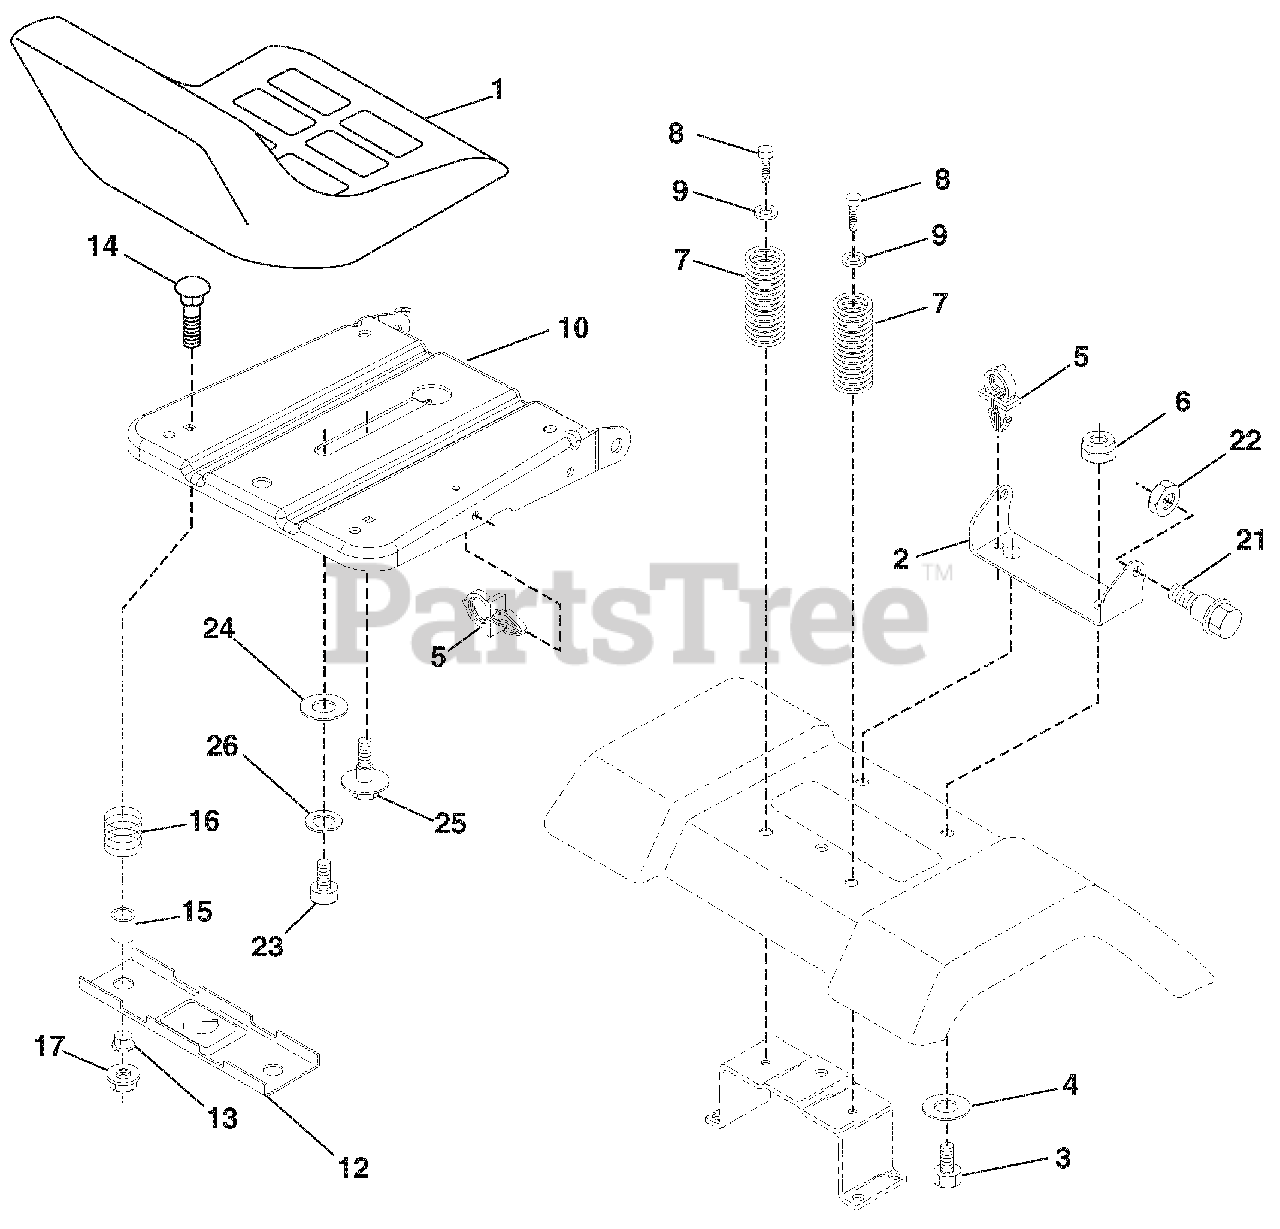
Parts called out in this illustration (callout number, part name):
2	Bracket Seat Pivot
3	Bolt Hex 3/8 - 16 x 1
4	Washer 13/32 x 1 x10 Ga.
5	CLIP.PUSH-IN.HINGED
6	Locknut, Washer Insert 3/8-16
7	SPRING.SEAT.CPRSN.2.250.BLK.ZI
8	SCREW.3/8-16X1.SMGML.TAP/R.BLK
9	Washer 13/32 x 1 x 14 Ga.
10	Pan Pnt Seat
12	Bracket Pnt Mounting Switch
13	BUSHING.SNAP.BLK.NYL..50 ID.
14	BOLT.RDHD.SHT.NK.1/4-20X1-1/2
15	SPACER.SPLIT..28X.96.YEL.ZINC
16	Spring Cprsn
17	NUT.LOCK.1/4 LGE.FLG.GR.5.ZINC
21	BOLT.SHLD.5/16-18 UNC-2A.BLK D
22	Locknut, Washer Insert 5/16-18
23	Bolt Hex
24	WASHER.17/32 X 1-3/16 X 12 GA.
25	Bolt Shoulder 5/16-18 x .62
26	Washer Lock Hvy Hlcl Spr 1/2
